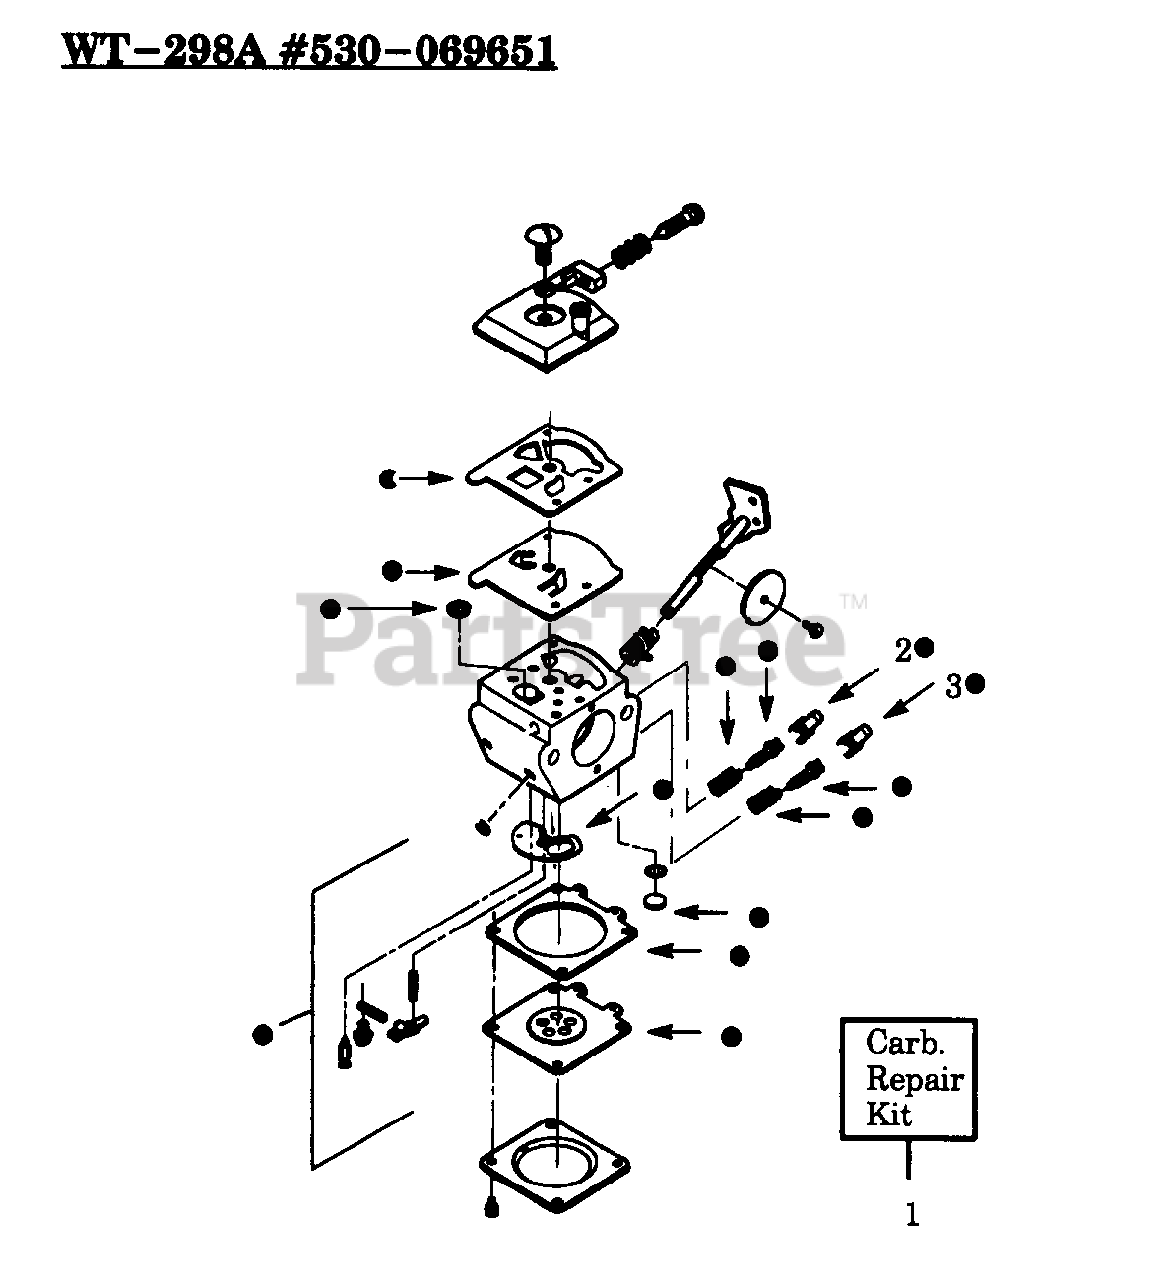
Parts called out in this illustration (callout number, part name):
1	Carburetor Repair Kit ( . Indicates Contents)
2	Limiter Cap-Low
3	Limiter Cap-High
